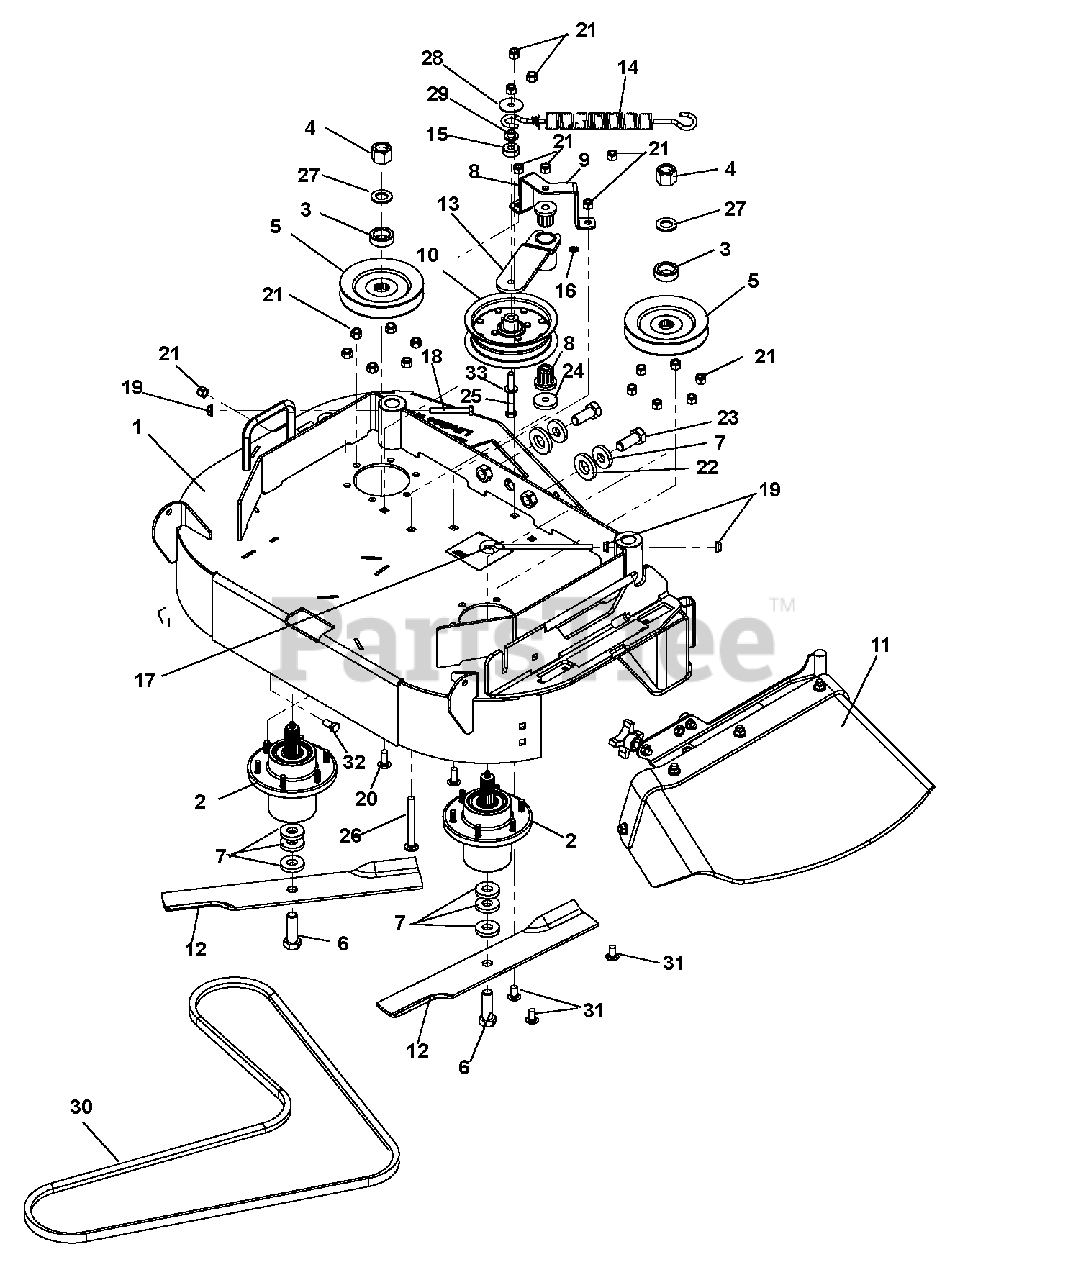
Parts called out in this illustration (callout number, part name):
1	Assembly, Deck 32" with Decals
2	Assembly, Spindle S/O
3	Spacer, 1.500 x 1.000 x .510 (SN 000101 – 020999)
4	Locknut, .75-16 Crown Grade 5
5	Pulley, Spline Spindle (SN 000101 – 021000)
6	Bolt, .62-11 x 2.00 Hex Grade 8
7	Washer, .630 x 1.50 x .25 Flat
8	Bearing, Flange M10 x M25 x M27 Fluted
9	Bracket, Idler Support
10	Pulley, Flat 5.0 x .38 w/BRG
11	Discharge Shield Assembly (see page 23 for individual parts)
12	Blade, 16.50" Lo-Lift
13	Weldment, Idler Arm w/Offset
14	Spring, Extension
15	Bushing, .380 x 1.00 x .410
16	Fitting, .25-28 Straight Grease Zerk
17	Bolt, Eye .31-18 x 5.50 .62 DIA
18	Bolt, .31-18 x 2.50 Hex Grade 8
19	Nut, Spinlock Flange .312-18
20	Bolt, .375-16 x 1.00 Round Head Square Neck
21	Nut, Locking-Nylon .38-16
22	Washer, .905 x 1.75 x .250
23	Bolt, Hex .625-11 1.50 Grade 8
24	Washer, .406 x 1.50 x .245 Flat
25	Bolt, .38-16 x 3.00 Hex Grade 5
26	Bolt, .375-16 x 3.75 Round Head Square Neck
27	Washer, .75 x 1.313 x .113
28	Washer, .380 x 1.50 x .062 Flat
29	Bushing,Flange .385 x .500 x .875 x .406
30	V-Belt, HB Wrapped
31	Bolt, Round Head Square Neck .38-16 x .75
32	Bolt, .38-16 x .750 Hex Grade 5
33	Washer, Flat-Steel .406 x .812 x .065
